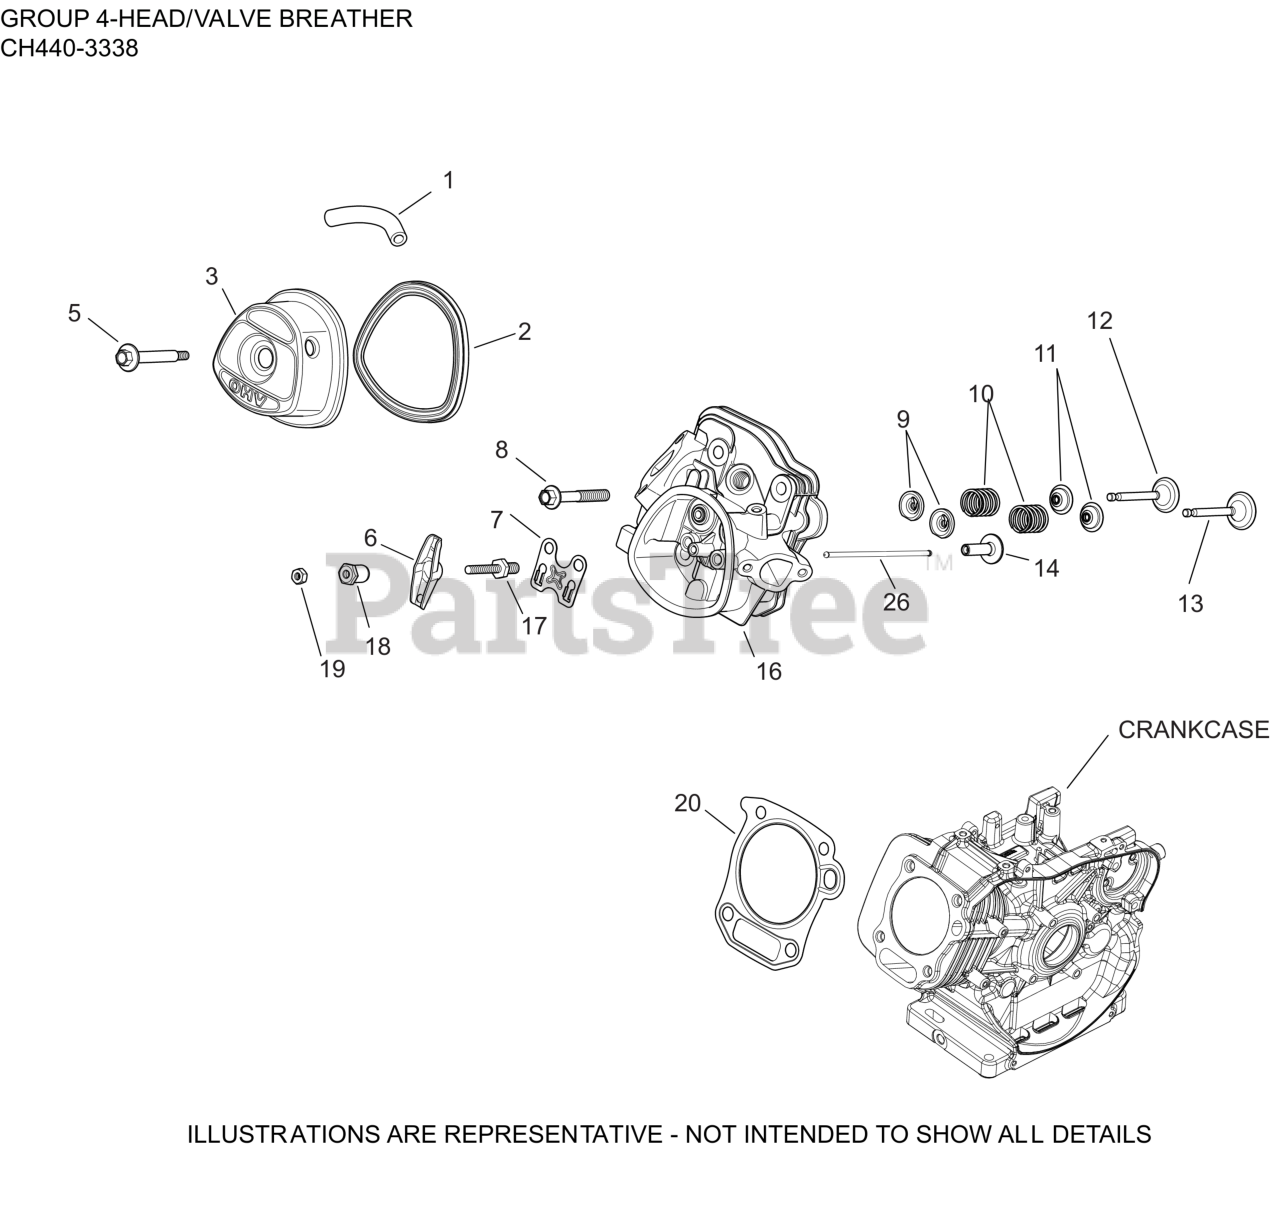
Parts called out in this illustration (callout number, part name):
1	TUBE, BREATHER
2	GASKET, VALVE COVER
3	KIT, VALVE COVER ASSEMBLY
5	SCREW, VALVE COVER SEAL ASSY
6	ARM, ROCKER
7	PLATE, PUSHROD GUIDE
8	SCREW, HEX FLANGE CYLINDER HEAD
9	RETAINER, VALVE SPRING
10	SPRING, VALVE
11	SEAL, VALVE STEM
12	VALVE, EXHAUST
13	VALVE, INTAKE
14	LIFTER, VALVE
16	KIT, HEAD ASSY
17	STUD, ROCKER ARM-USE 14 072 22-S
18	PIVOT, ROCKER ARM
19	NUT, HEX JAM
20	KIT, HEAD GASKET
26	ROD, PUSH
